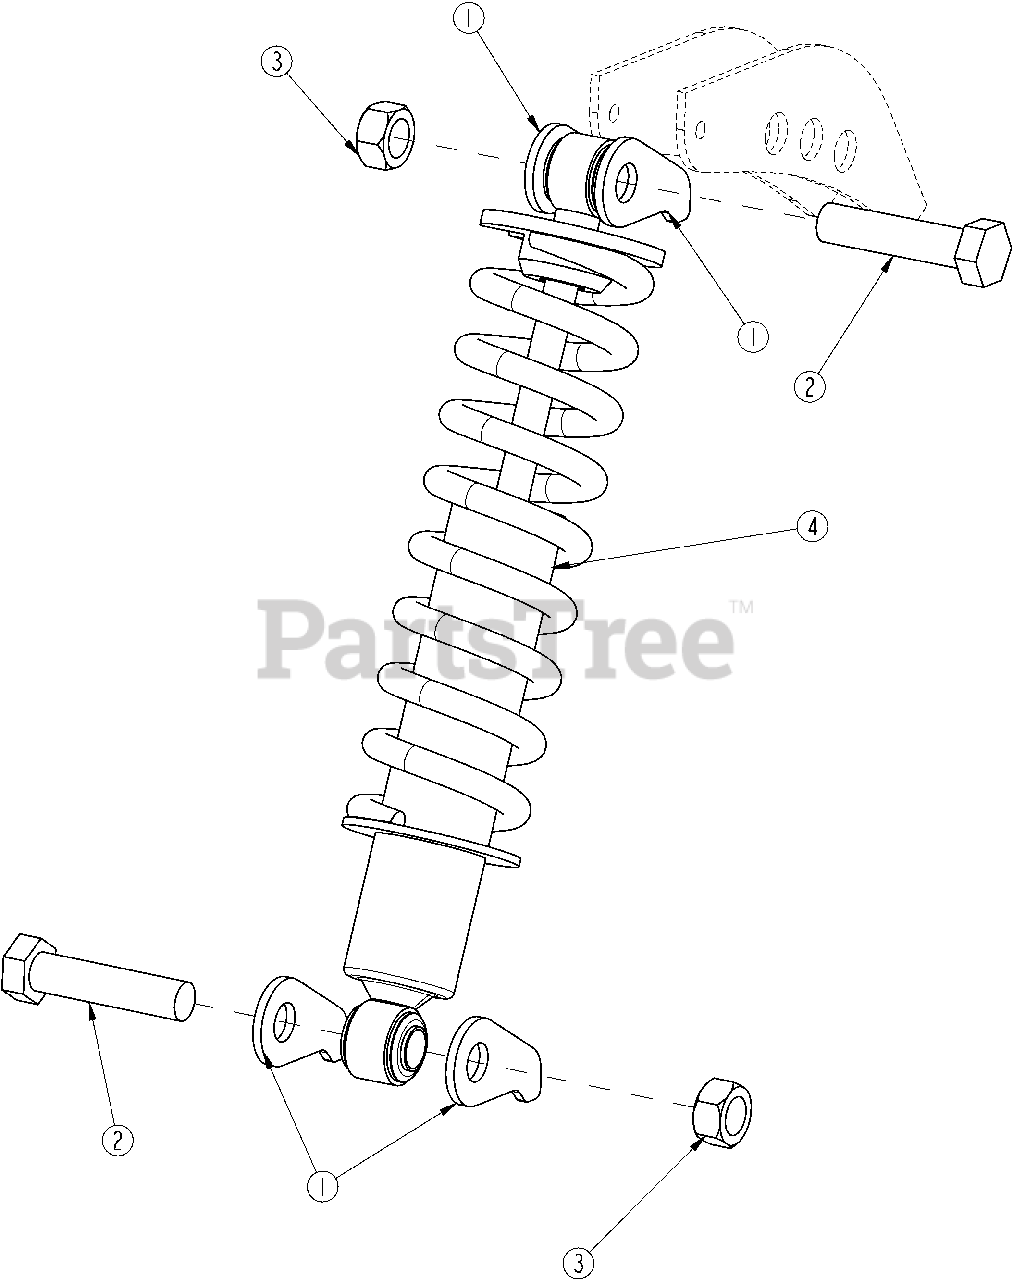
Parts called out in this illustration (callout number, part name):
1	SHOCK SPACER PLATE
2	HHCS M14X2.00X60 GR8.8
3	NUT HEX NYLOCK M14X2.00
4	SHOCK COIL REAR TRUCK
